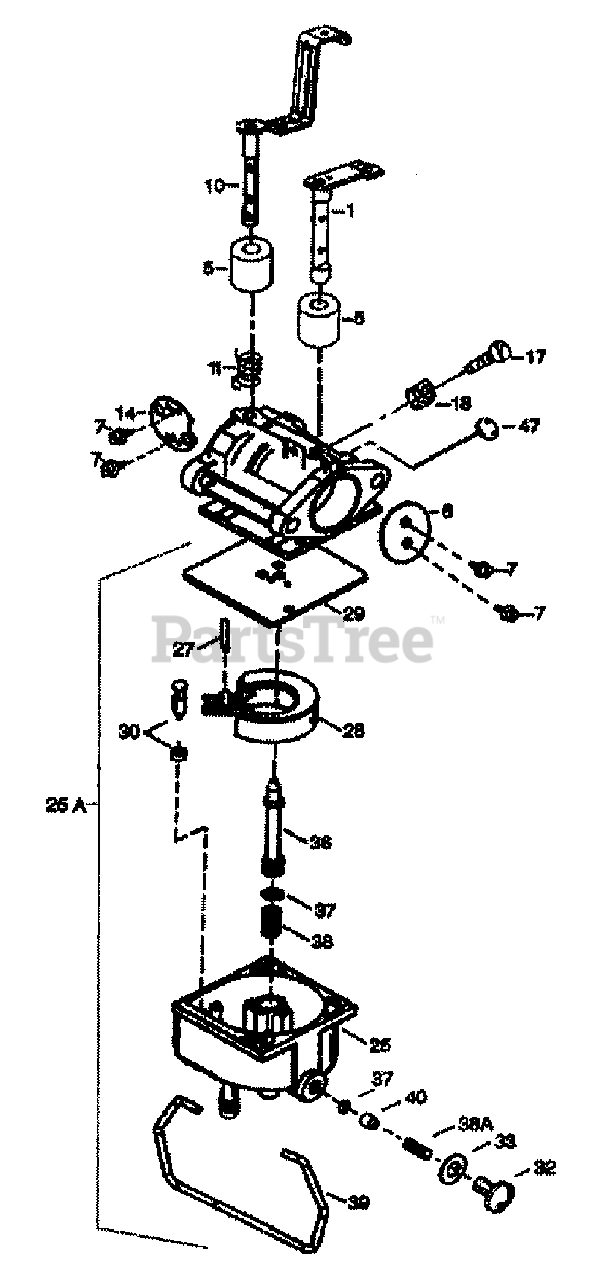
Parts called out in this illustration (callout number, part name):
1	Throttle Shaft & Lever Assembly
6	Throttle Shutter
7	Throttle & Choke Shutter Screws
10	Choke Shaft & Lever Assembly
11	Choke Return Spring
14	Choke Shutter
17	Throttle Crack Screw/Idle Speed Screw
18	Tension Spring
25	Float Bowl Assembly
25A	Float Bowl Repair Kit
29	Float Bowl to Body Gasket
30	Inlet Needle & Seat
32	Bowl Drain Screw
33	Bowl Drain Washer
36	Main Nozzle Tube
37	O-Ring
38	Spring, Main Nozzle Tube
39	Float Bowl Retainer
40	Main Fuel Jet
47	Welch Plug, Idle Mixing Well
